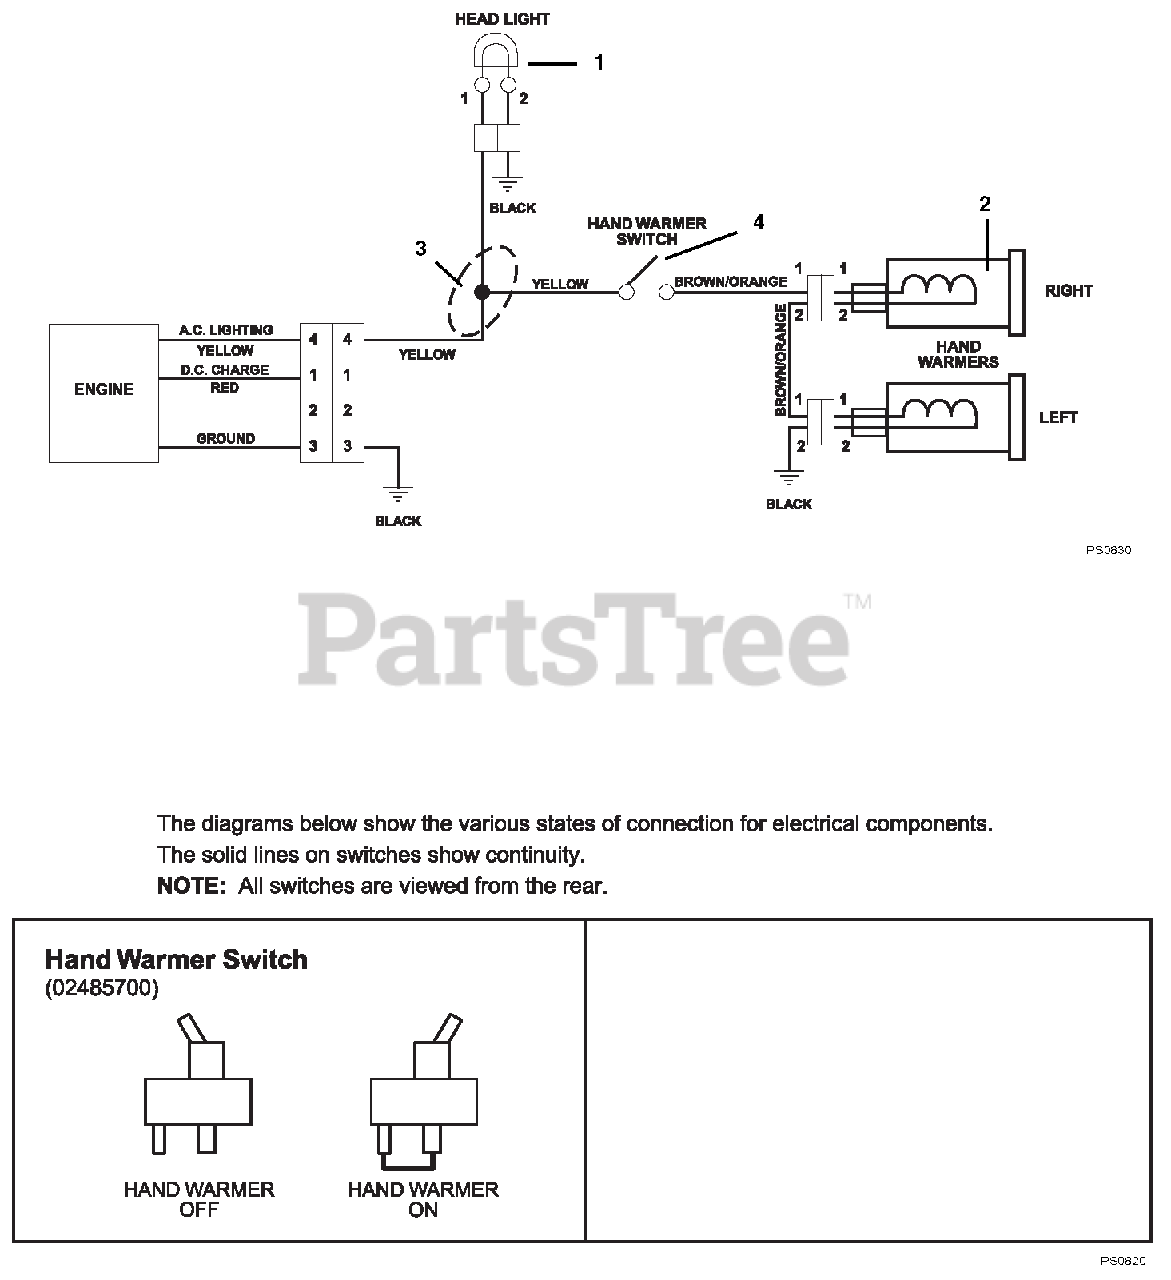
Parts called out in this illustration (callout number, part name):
1	LIGHT, HALOGEN ASSY.
2	HEATED GRIP, MAGURA
3	HARNESS, LIGHT&HW, 2 PIN W/GRD
4	SWITCH, ON/OFF
